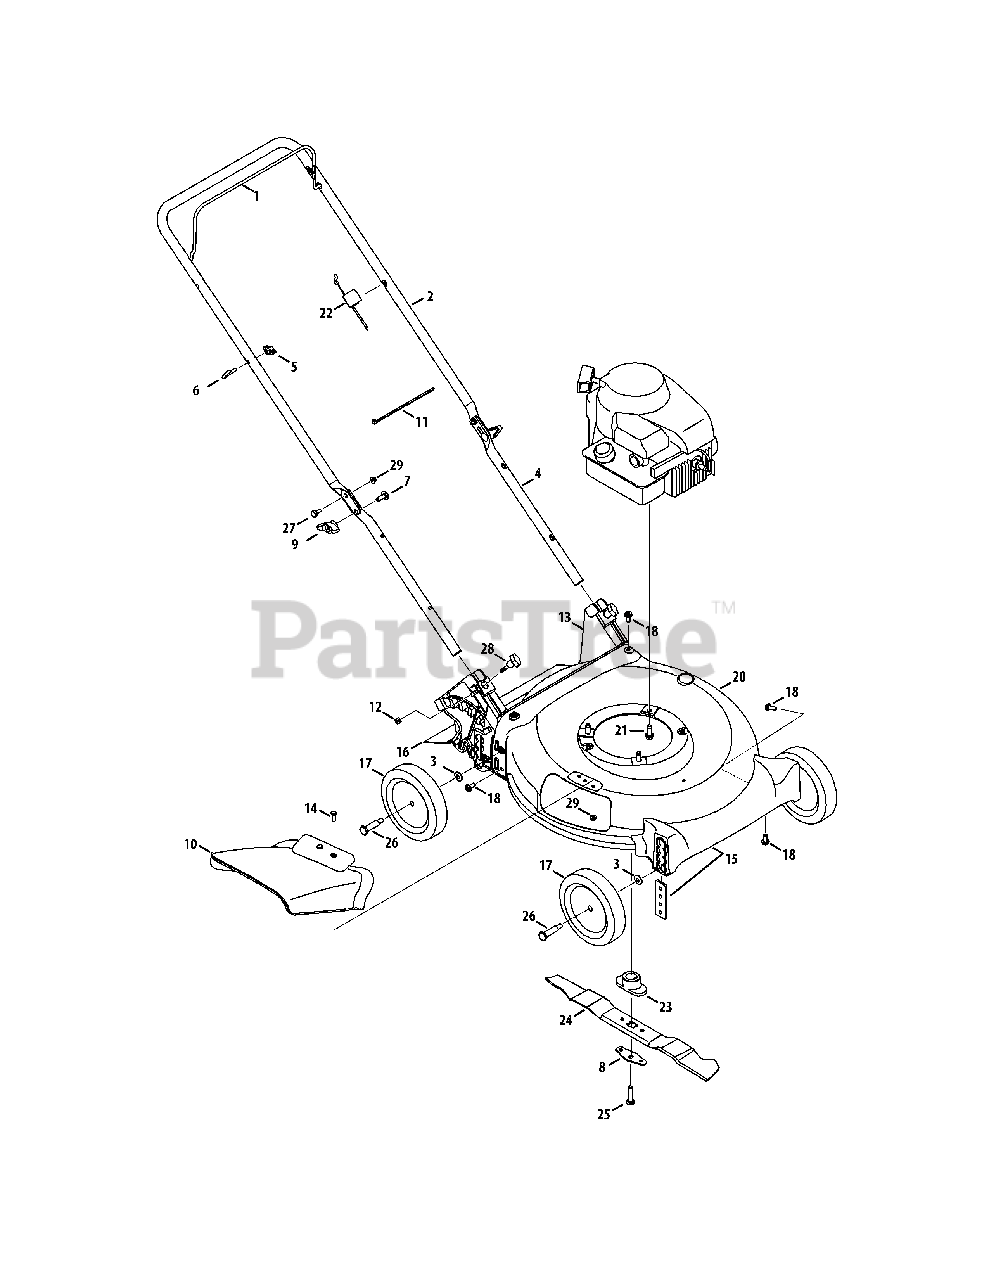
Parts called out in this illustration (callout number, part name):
1	Blade Control Handle - Black
2	Upper Handle - Black (adjustable)
3	Cupped Washer
4	Lower Handle
5	Knob 1/4-20
6	Rope Guide Bolt
7	Carriage Bolt 5/16-18
8	Blade Bell Support
9	Wing Knob 5/16-18 Black
10	Chute Deflector
11	Cable Tie
12	Sq. Nut 1/4-20
13	Rear Baffle Ass’y
14	Hex. Hd. Cap Scr. 1/4-20 x .75
15	Front Axle Cover
16	Trailing Shield 4.54 x 17.37
17	Wheel Ass’y 7 x 1.5 Diamond Star
18	Hex Hd. Cap Scr. 5/16-14 x .75
20	21" Deck Ass’y
21	Hex Wash HD Tap Scr 3/8-16 x 1.0
22	Control Cable, 125 cc B&S
23	Blade Adapter
24	21" Mulching Blade
25	Hex Bolt 3/8-24 x 1.5" Lg. (Gr 8)
26	Shoulder Screw .498 x 1.6
27	Shoulder Screw .375 x .126 x 1/4-20
28	Knob 1/4-20 x 1.725 Black
29	Flanged Lock Nut 1/4-20 Gr. F Nylon
